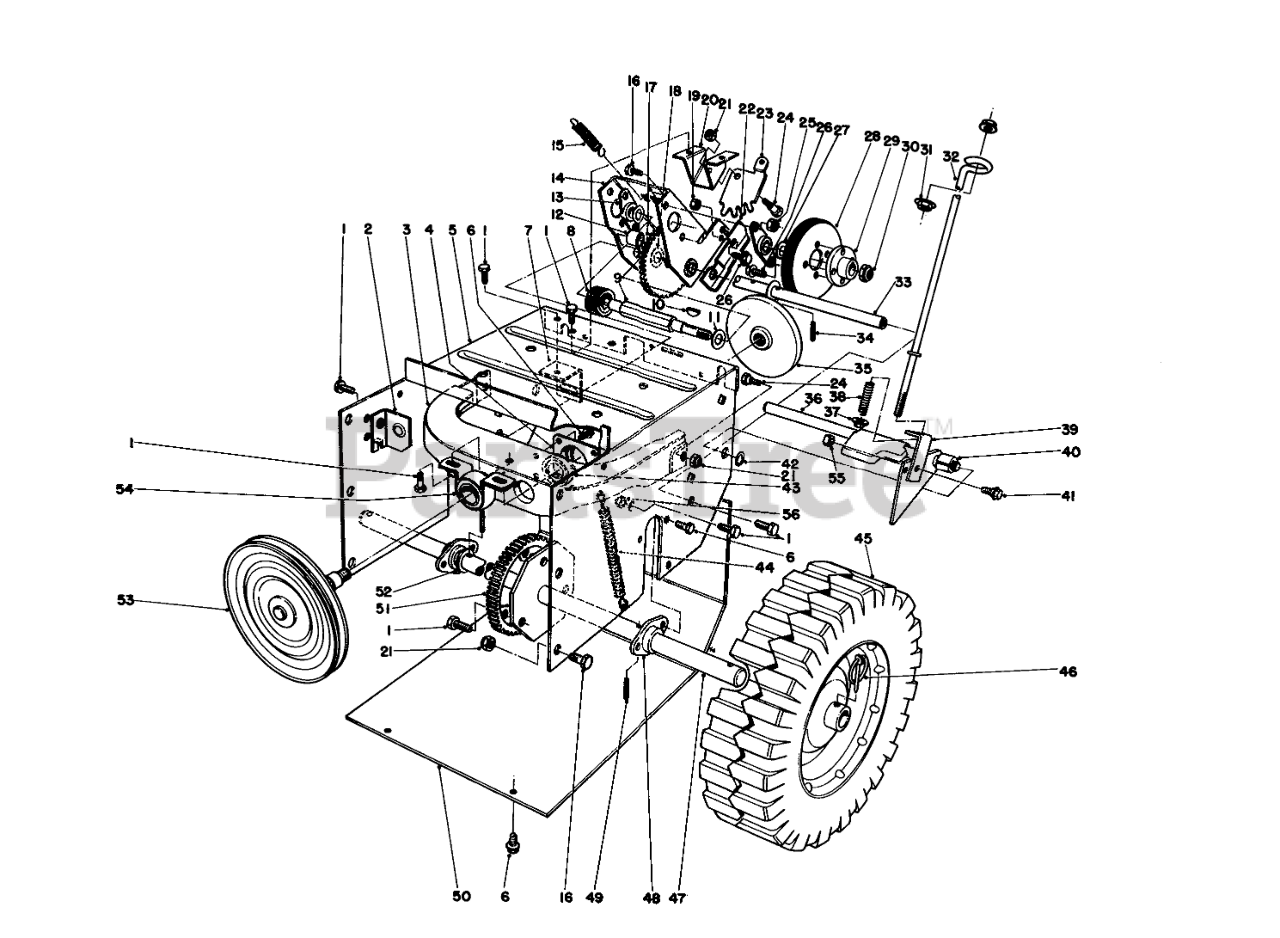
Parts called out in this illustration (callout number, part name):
1	SCREW-HWHTF
2	AUGER CLUTCH MTG FRT
3	"OBS" FRICTION PLT FRAME
4	CUP-BEARING
5	Frame-Traction
6	SCREW
7	BRACKET-MOUNT, REAR
8	PINION
9	SHAFT-WHEEL, FRICTION
10	KEY-WOODRUFF
11	WASHER-FLAT
12	5/8ID X 1LG BUSHING
13	BEARING-WHEEL, FRICTION
14	BRACKET-SLIDING
15	SPRING-TRACTION
16	SCREW-HH
17	Intermediate Gear & Bushing (Incl. Ref. #12)
18	WASHER-SPECIAL
19	NUT-LOCK, NI
20	MOUNT-LEVER
21	NUT-LOCK, NI
22	CAM-RECEIVER
23	GEAR-QUADRANT
24	BOLT-SHOULDER
25	NUT-LOCK, CONE
26	Screw
27	WASHER-THRUST
28	WHEEL-FRICTION
29	HUB-WHEEL, FRICTION
30	NUT-LOCK, NI
31	NUT-HF
32	ROD-TRACTION, LOWER
33	SHAFT-PIVOT
34	PIN-SPRING
35	PLATE-FRICTION
36	Traction Engagement Asm.
37	NUT-LOCK, HHF
38	SPRING
39	BRACKET-TRACTION
40	SPACER
41	SCREW
42	RING-RETAINING
43	BEARING-BALL
44	SPRING-PLATE, FRICTION
45	Wheel
46	PIN-LYNCH
47	AXLE SHAFT WA
48	BEARING-AXLE
49	PIN-SPRING
50	Bottom Cover
51	GEAR-AXLE
52	WASHER-THRUST
53	Pulley & Shaft
54	BUSHING ASM
55	NUT-LOCK, NI
56	NUT-LOCK, CAP
